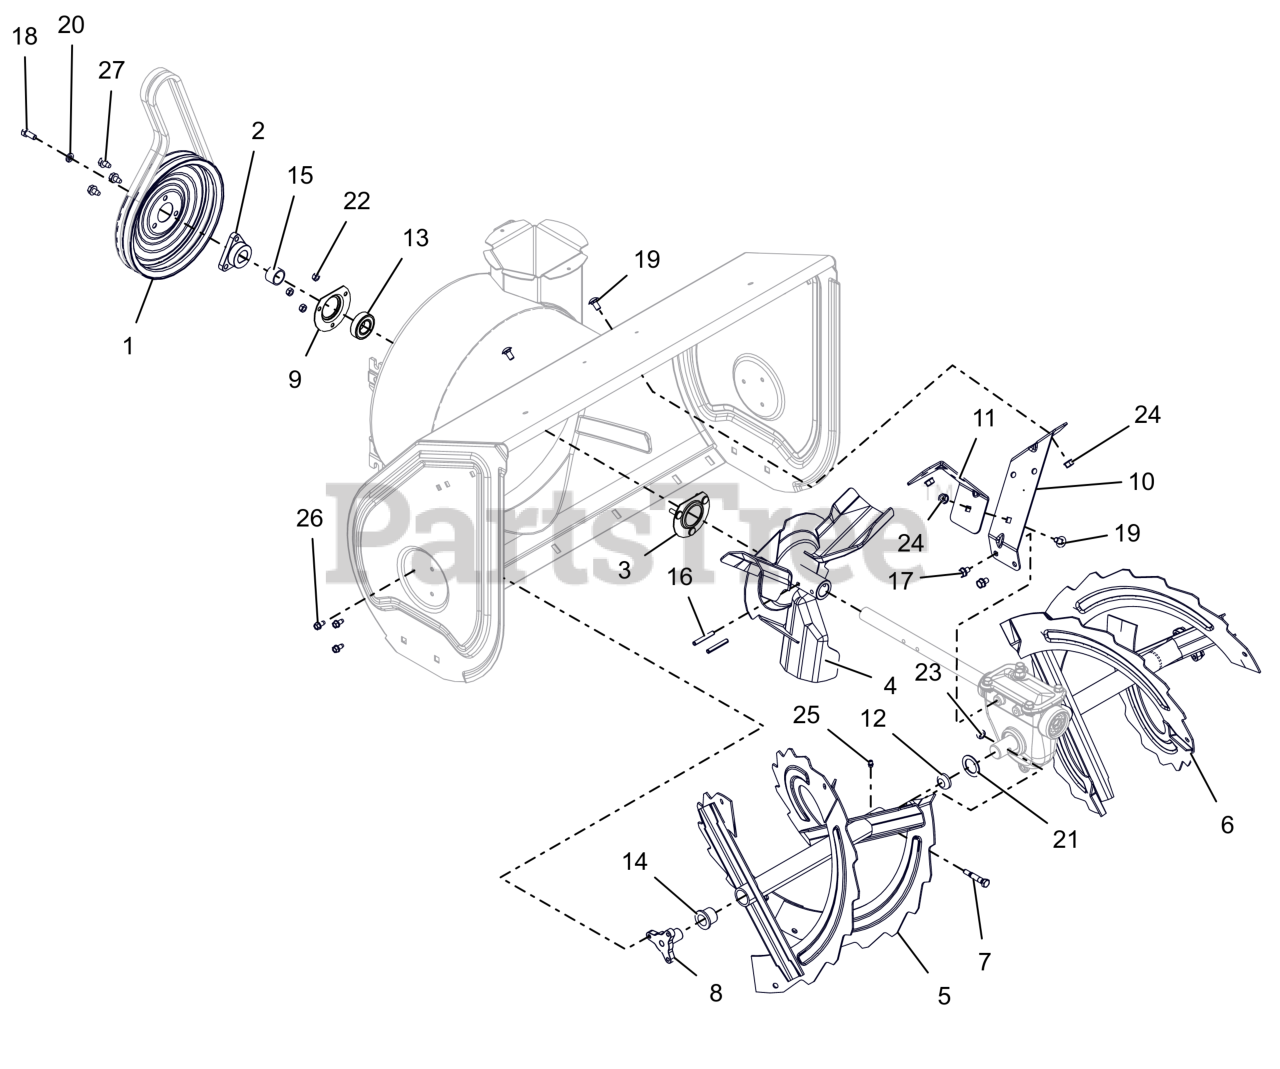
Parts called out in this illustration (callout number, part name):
1	PULLEY, SPIN FORM DUAL GROOVE
2	PULLEY HUB, D-BORE .87 PRO
3	BEARING FLANGE
4	IMPELLER, 3 BLADE-14"
5	RAKE, RH W/ZERK - 30"
6	RAKE, LH W/ZERK - 30"
7	SHEAR BOLT SERVICE ASSEMBLY
8	SUPPORT, RAKE BUSHING
9	BEARING FLANGE
10	BRACKET, GEARCASE SUPPORT - LH
11	BRACKET, GEARCASE SUPPORT - RH
12	PLUG, RAKE TUBE
13	BRG-BALL .876 X 1.750 X .50
14	BSHG-FLG, NY.778 ID X 1.018 OD
15	BSHG,SPCR .895X1.065X.693
16	PIN-ROLL .250X1.75
17	BLT, SEMS .31-18X.50 G5 ZCC
18	BLT, HEX .31-24X.750 G5 ZCC
19	BLT,RHSSN.31-18X.625 G5 ZCCP30
20	WSHR, LK-HVY .312X.097 ZCC
21	WSHR, FLT 1.010X1.505X.062 ZCC
22	NUT,LK-CTR .25-20 GA ZCC
23	NUT,LK-CTR .31-18 GA ZCC
24	NUT-LK-TOP-FLG .312-18 GF ZCC
25	ZERK,FITTING .25X.125 DRIVE IN
26	SCR-TAP .25-20X.50 HWH ZCC
27	SCR,TAP .312-18X.50 HWH TR ZCC
